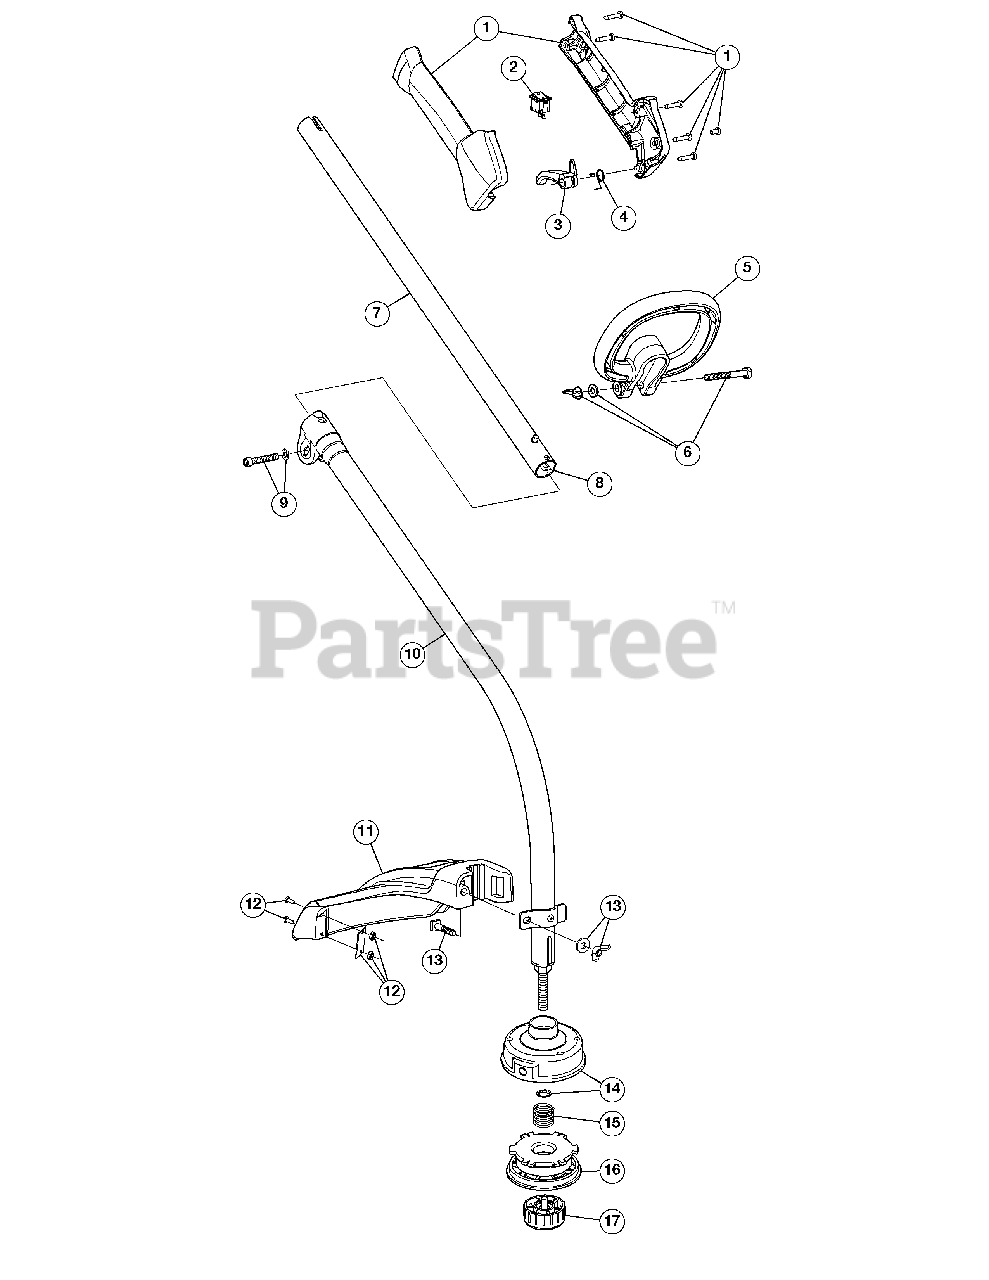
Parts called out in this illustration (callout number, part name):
1	Throttle Housing Assembly (Incl. 2 - 4)
2	Switch Assembly
3	Throttle Trigger
4	Throttle Trigger Spring
5	D-Handle (Incl. 6)
6	D-Handle Hardware Assembly
7	Upper Shaft Housing Assembly (Incl. 8)
8	Upper Flexible Drive Shaft
9	Clamp Hardware
10	Lower Shaft Housing Assembly (Incl. 9 & 14)
11	Shield Assembly (Incl. 12 & 13)
12	Blade Assembly
13	Shield Mounting Hardware
14	Outer Spool with Retainer
16	Inner Reel
17	Bump Knob Assembly
